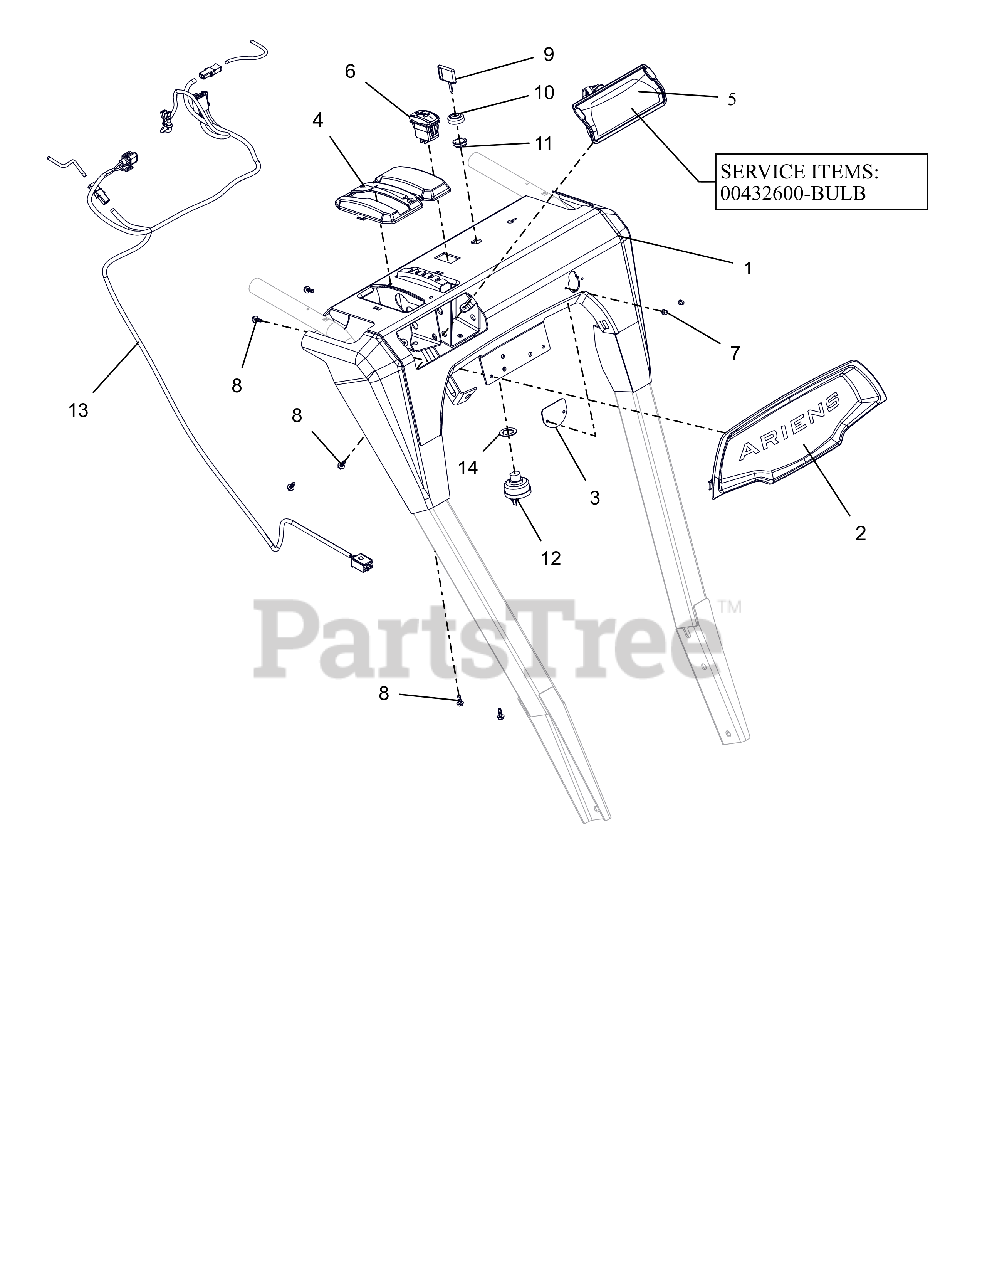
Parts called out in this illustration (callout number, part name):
1	PANEL, DASH - W/CTR DECAL(12V)
2	BEZEL, DASH - ARIENS LG DASH
3	COVER, DASH BRKT, BRUSH
4	BEZEL, SHIFT - HYDRO BRUSH
5	HEADLIGHT ASY, HALO 20W 2SHOT
5	BULB, LIGHT-HALOGEN 20W
6	SWITCH,ROCKER SPST-ON/OFF
7	RVT-POP #43 .125X.313 STL ZINC
8	SCR-TAP #10X.50 BOSS INDHXHD
9	KEY -W/CAP
10	CAP - IGNITION SWITCH
11	NUT-PANEL .625-32 GRECO
12	IGNITION SWITCH ASSEMBLY
13	HARNESS,ELEC - HANDLEBAR 12V
14	WSHR-LK-INT .625X.045 YWZC
